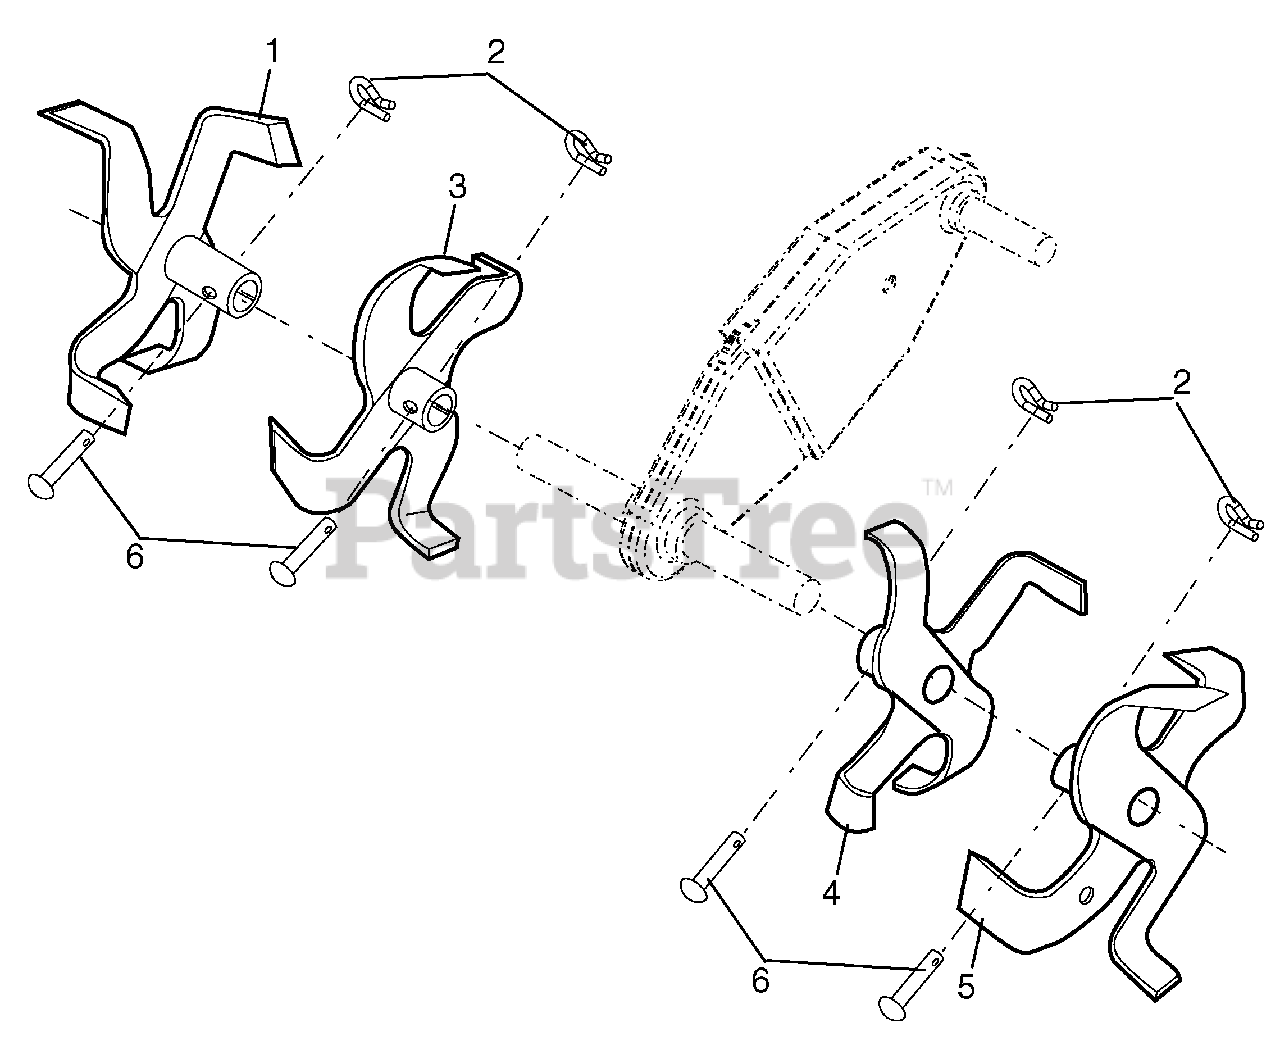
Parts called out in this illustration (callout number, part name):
1	Tine, Outer, R.H.
2	Retainer, Spring
3	Tine, Inner, R.H.
4	Tine, Inner, L.H.
5	Tine, Outer, L.H.
6	Pin, Clevis
